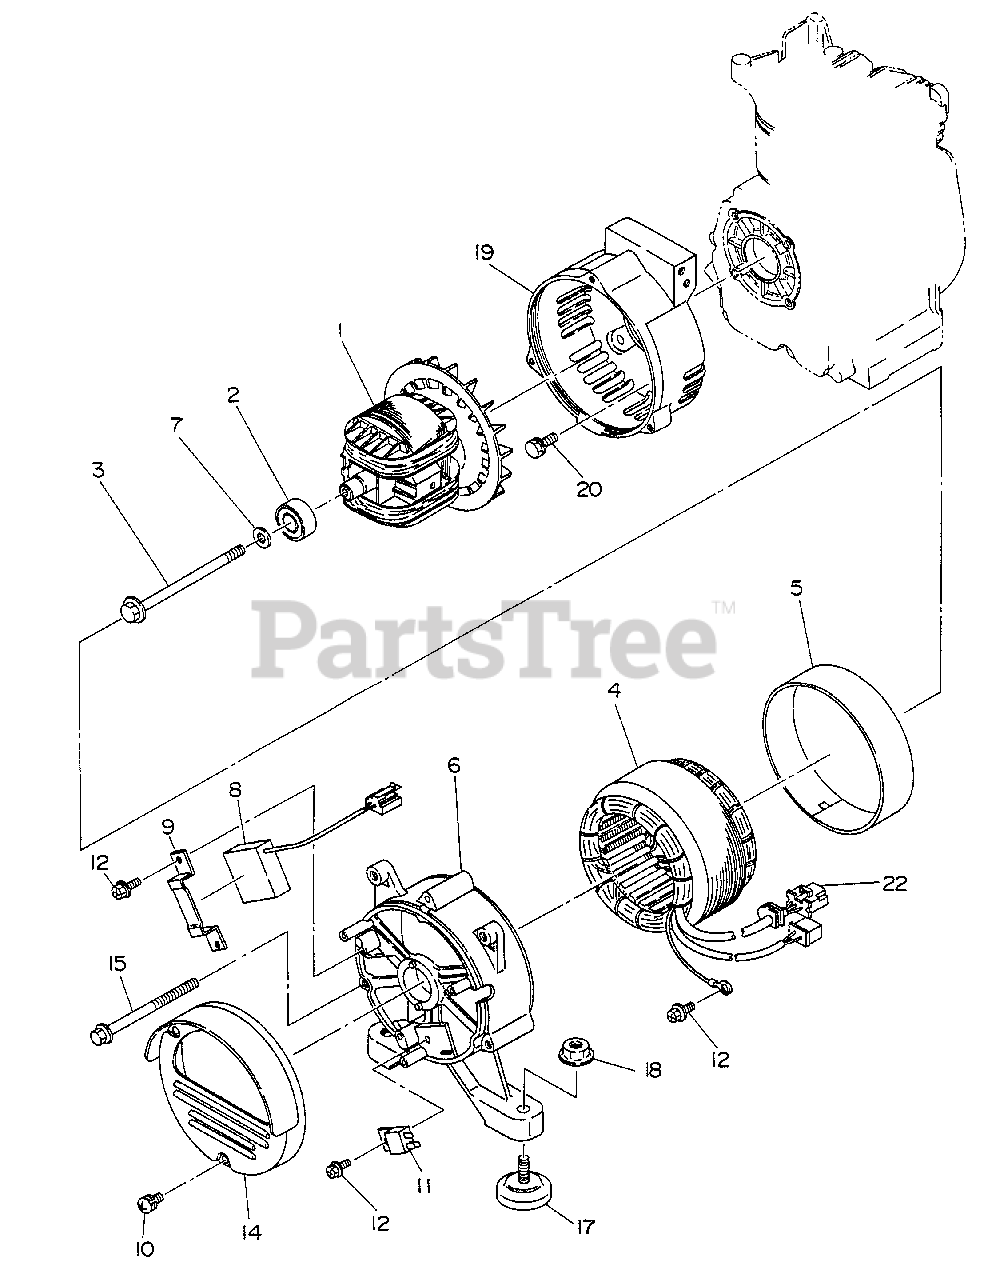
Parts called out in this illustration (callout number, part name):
1	ROTOR ASSY
2	BEARING, BALL
3	THROUGH BOLT
4	STATOR ASSY
5	STATOR COVER
6	BRACKET, REAR
7	WASHER
8	CONDENSER
9	CONDENSER BRACKET
10	SCREW
11	RECTIFIER
12	SCREW
14	END COVER COMPL.
15	COVER, BOLT
17	MOUNT ASSY
18	NUT, FLANGE
19	FRONT COVER
20	BOLT
22	CONNECTOR
